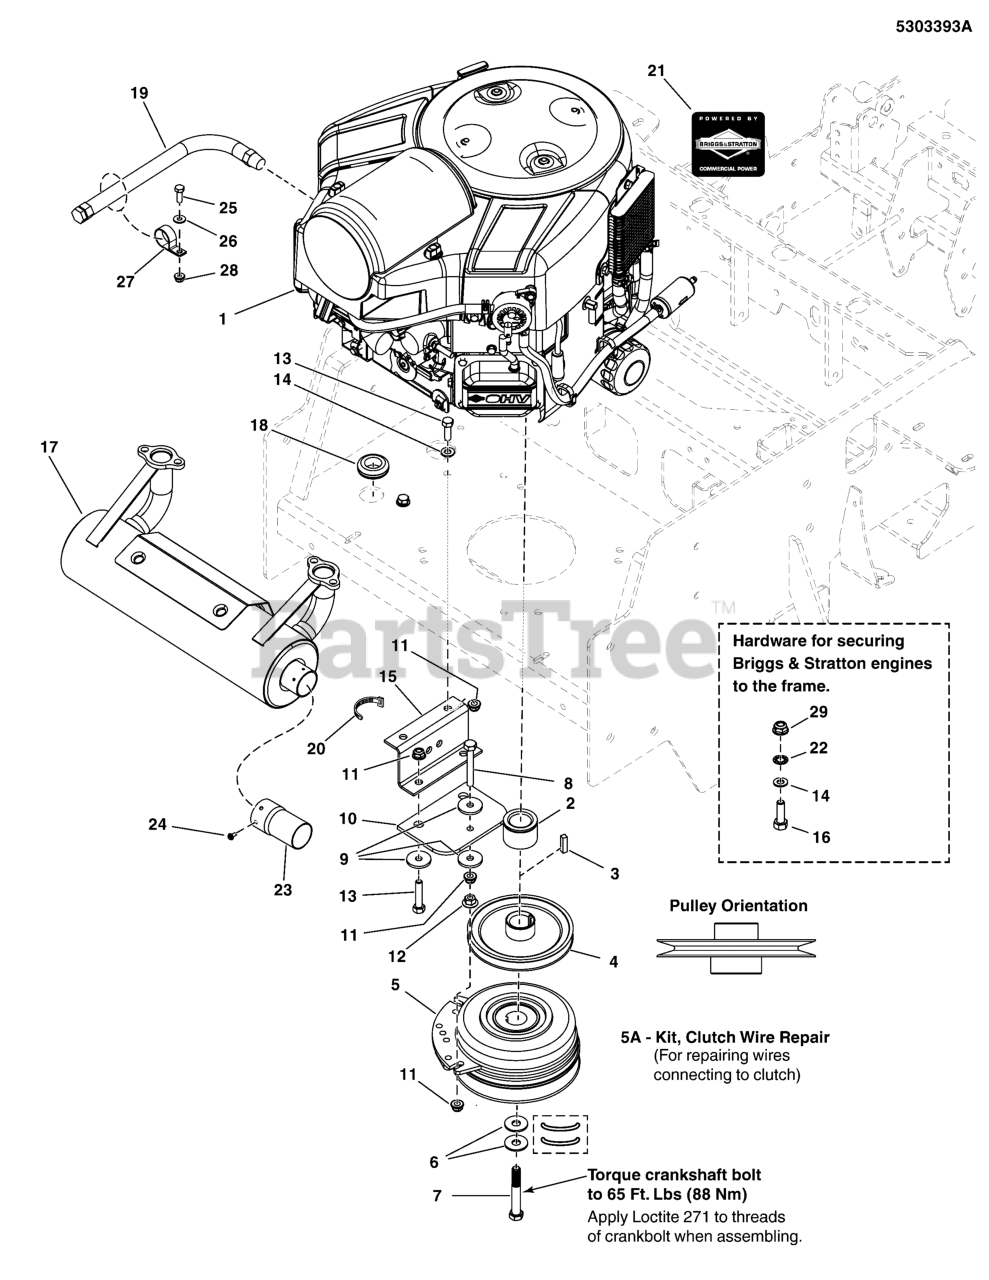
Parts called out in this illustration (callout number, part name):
2	SPACER, 1.13 X 1.75 X 1.25
3	KEY 1/4 SQ X 1 1/2 LONG
4	PULLEY,CRANKSHAFT,1.125ID X 5.5OD A SECT
5	CLUTCH,5218-221, WARNER
5A	KIT, CLUTCH WIRE REPAIR
6	BELLEVILLE WASHER 1.1875 X .442 X .089
7	BOLT, CRANKSHAFT, 7/16-20 X 3, GD8
8	BOLT, 5/16-18 X 2 GD5 TFL, CZ
9	WASHER, .34 X 1.25 X 10 GA
10	CLUTCH ANCHOR PAD
11	NUT, 5/16-18 HEX NYLOCK FLANGE
12	NUT, 5/16-18 HEX SERRATED FLANGE (LARGE)
13	BOLT, 5/16-18 X 1 GD5 YZ
14	WASHER, 5/16" SAE
15	ANCHOR, CLUTCH, S125XT - BLK
16	BOLT, 5/16-24 X 1-3/4, GD8
17	MUFFLER, RIGHT OUTLET ASSY
18	GROMMET, 7/8
19	HOSE, OIL DRAIN
20	TIE,SELF-LOCKING, 24"
22	WASHER, 5/16 INT. TOOTH LOCK
23	EXTENSION, TAILPIPE, 3" - BLACK
24	SCREW,SELF-TAP,#8-32 X 3/8, WASH HEX, CZ
25	BOLT, 1/4-20 X 3/4 GD5 YZ
26	WASHER, 1/4 SAE
27	CLAMP, VINYL INSULATED
28	NUT, 1/4-20 HEX NYLOCK FLANGE
29	NUT, 5/16-24, NYLOCK FLANGE, GD8, CZ
